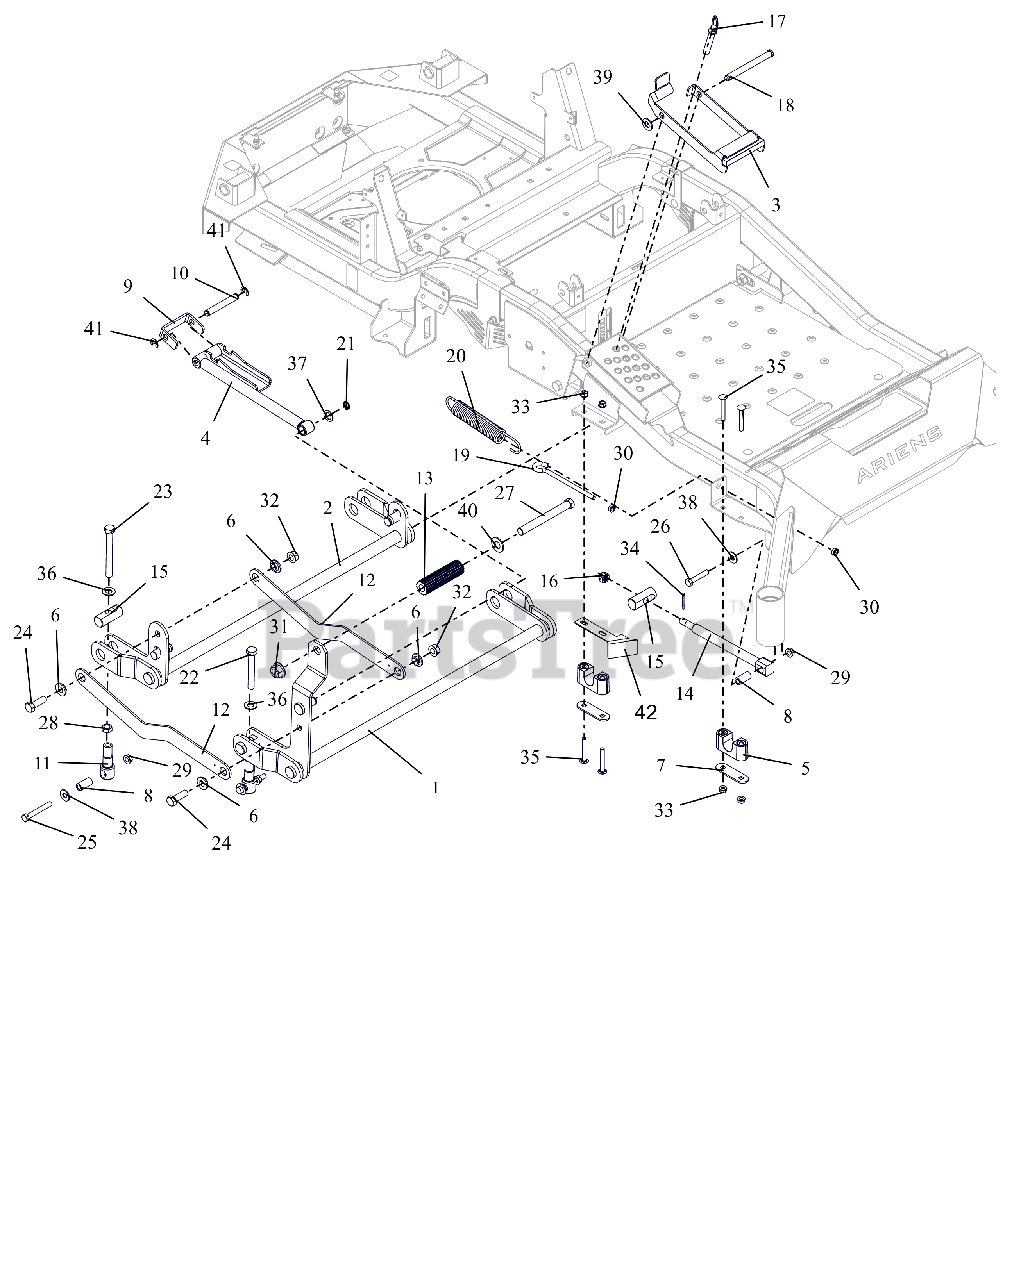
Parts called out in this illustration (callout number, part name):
1	WLDMT, FRONT DECK LIFT PIVOT
2	WLDMT, REAR DECK LIFT PIVOT
3	BRKT, HOC TRANSFER LOCK
4	WLDMT, HOC ARM
5	ASM-BUSHING, DECK LIFT
6	BSHG-FLG .515X.750X.395X1.120
7	PLATE, BEARING SUPPORT
8	SPACER, DECK LEVELING
9	BRKT, HOC LINE
10	ROD, HOC PIVOT
11	LINK, DECK LIFT FORMED
12	LINK, DECK LIFT
13	ROD, FOOT PEDAL (BLACK)
14	DRAG,LINK-HD
15	PIN, DECK LIFT
16	NUT-SL .50-13
17	PIN, .50 X 2.20 USABLE LG BALL
18	PIN-SLIC .50X4.97X4.55 -ZCC
19	BOLT,.38-16 X 5.25-.62 DIA EYE
20	SG-TENS .162X1.25X8.25 WLD 25
21	RG-RTNG-EXT .625X.050
22	BLT, HEX .50-13X3.50F G5 ZCC
23	BLT, HEX .50-13X4.50F G8 ZCC
24	BLT,HEX .50-13X1.50 G5 ZCC
25	BLT, HEX .38-16X2.75 G8 ZCC
26	BLT,HEX .38-16X2.00 G5 ZCC
27	BLT, HEX .62-11X5.50 G5 FBP
28	NUT-JAM .500-13 G2 ZCC
29	NUT-LK-TOP-FLG .38-16 ZC120
30	NUT-JAM .375-16 G2 ZCC
31	NUT,FLG-TOP LK .625-11 FBP
32	NUT-LK-TOP-FLG .500-13 GF ZCC
33	NUT,LK-CTR-FLG .31-18 GF ZCC
34	PIN,CTR.12X1.25EXTPRSQCT ZC120
35	BLT, RHSSN.31-18X2.25 G5 ZCC
36	WSHR, FLT .557X1.040X.102 ZCC
37	WSHR, FLT .630X1.005X.062 ZCC
38	WSHR,FLT .438X1.00X.083 ZCC
39	WSHR,FLT .531X1.062X.095 ZCC
40	WSHRFLT 5/8SAE CARBHARD FBP
41	RG-RTNG-EXT .500X.042 (E)
42	GUARD, STOP CE 60 (BLACK)
